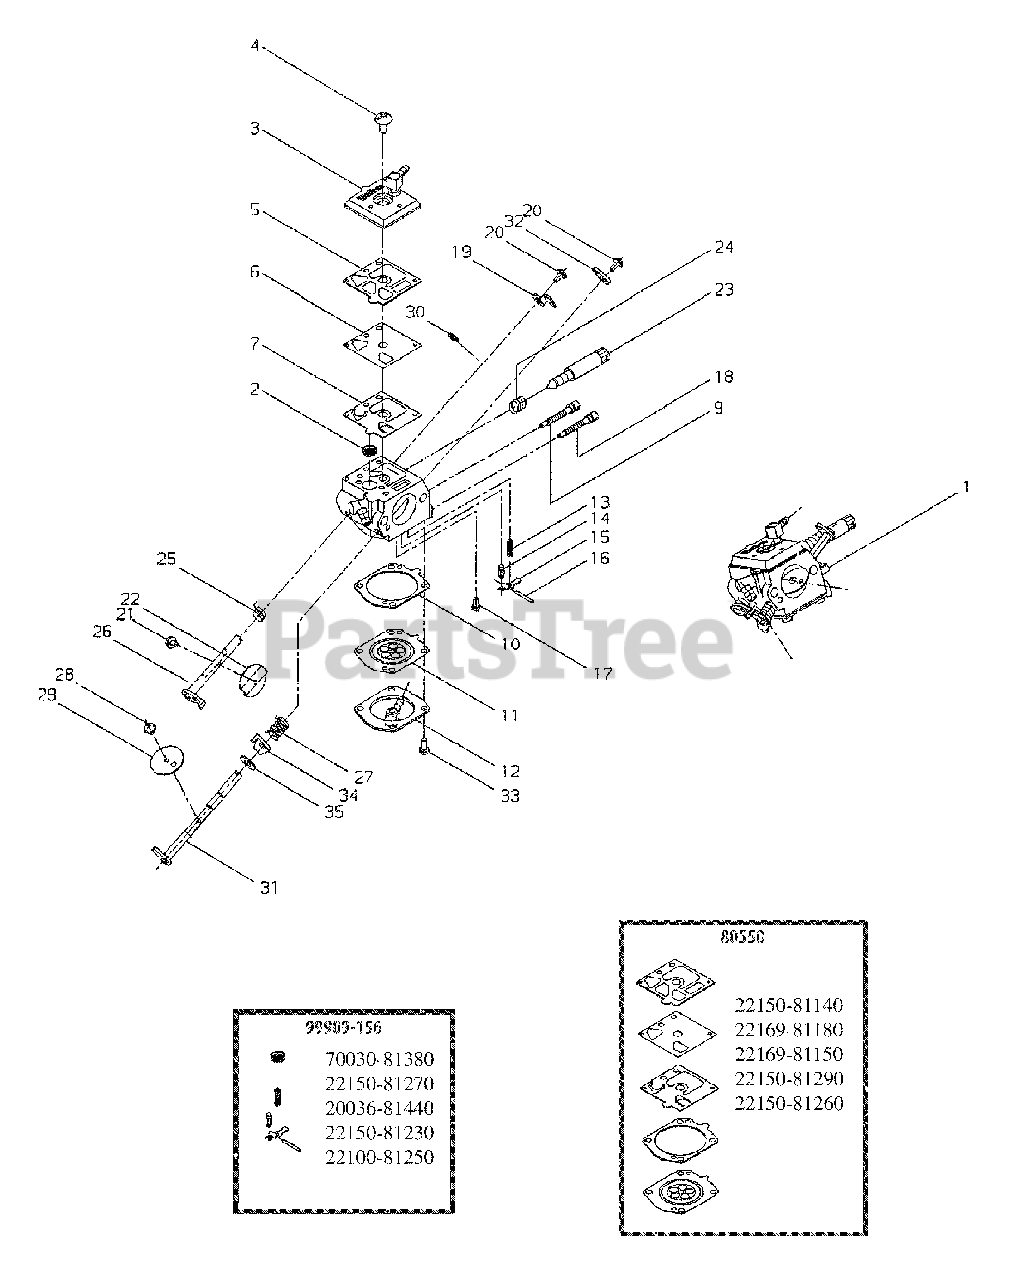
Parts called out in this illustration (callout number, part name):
1	CARBURETOR
2	SCREEN, FUEL INLET
3	COVER ASSY, PUMP
4	SCREW
5	GASKET, FUEL PUMP
6	DIAPHRAGM, PUMP
7	DIAPHRAGM, PUMP
9	NEEDLE, HIGH SPEED
10	GASKET, METERING DIAPHRAGM
11	DIAPHRAGM, METERING
12	COVER, DIAPHRAGM
13	SPRING, METERING LEVER
14	VALVE, INLET NEEDLE
15	LEVER, METERING
16	PIN, METERING LEVER
17	SCREW, METERING LEVER PIN
18	NEEDLE, HIGH SPEED
19	STOP, THROTTLE
20	SCREW
21	SCREW, THROTTLE VALVE
22	VALVE, THROTTLE
23	SCREW, IDLE ADJUST
24	SPRING, IDLE ADJUST
25	SPRING, THROTTLE RETURN
26	SHAFT, THROTTLE
27	SPRING, CHOKE RETURN
28	SCREW, THROTTLE STOP
29	VALVE, CHOKE
30	E-RING
31	SHAFT, CHOKE
32	LEVER, THROTTLE
33	SCREW
34	LEVER, FAST IDLE
35	WASHER
80550	DIAPHRAGM/GASKET KIT
99909-156	REPAIR KIT
